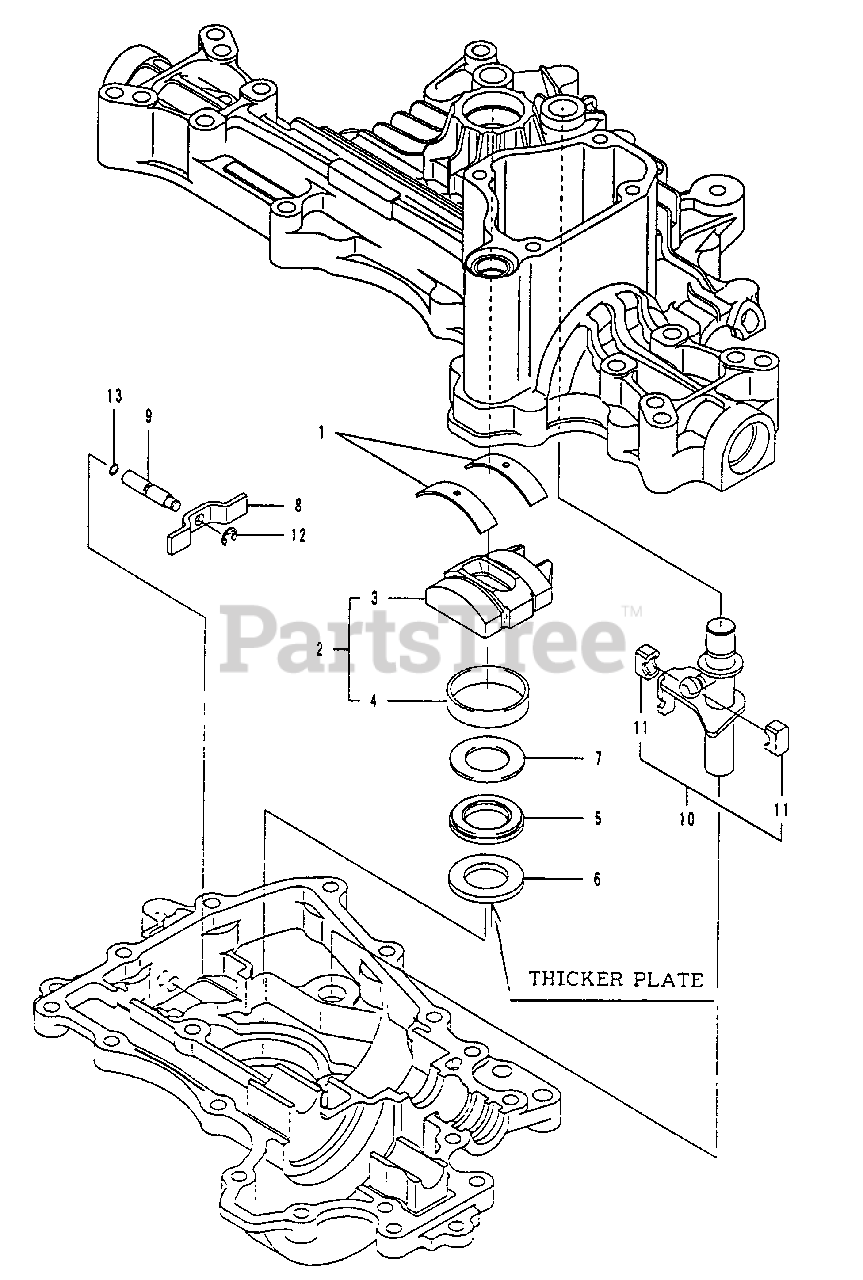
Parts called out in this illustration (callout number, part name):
1	THRUST METAL
2	SWASH PLATE CMP.
3	SWASH PLATE
4	BUSHING (PUMP
5	BEARING K81105
6	THRUST PLATE (A
7	THRUST PLATE (B
8	C ARM (BYPASS
11	BLOCK (SHIFT
13	PACKING P 5
